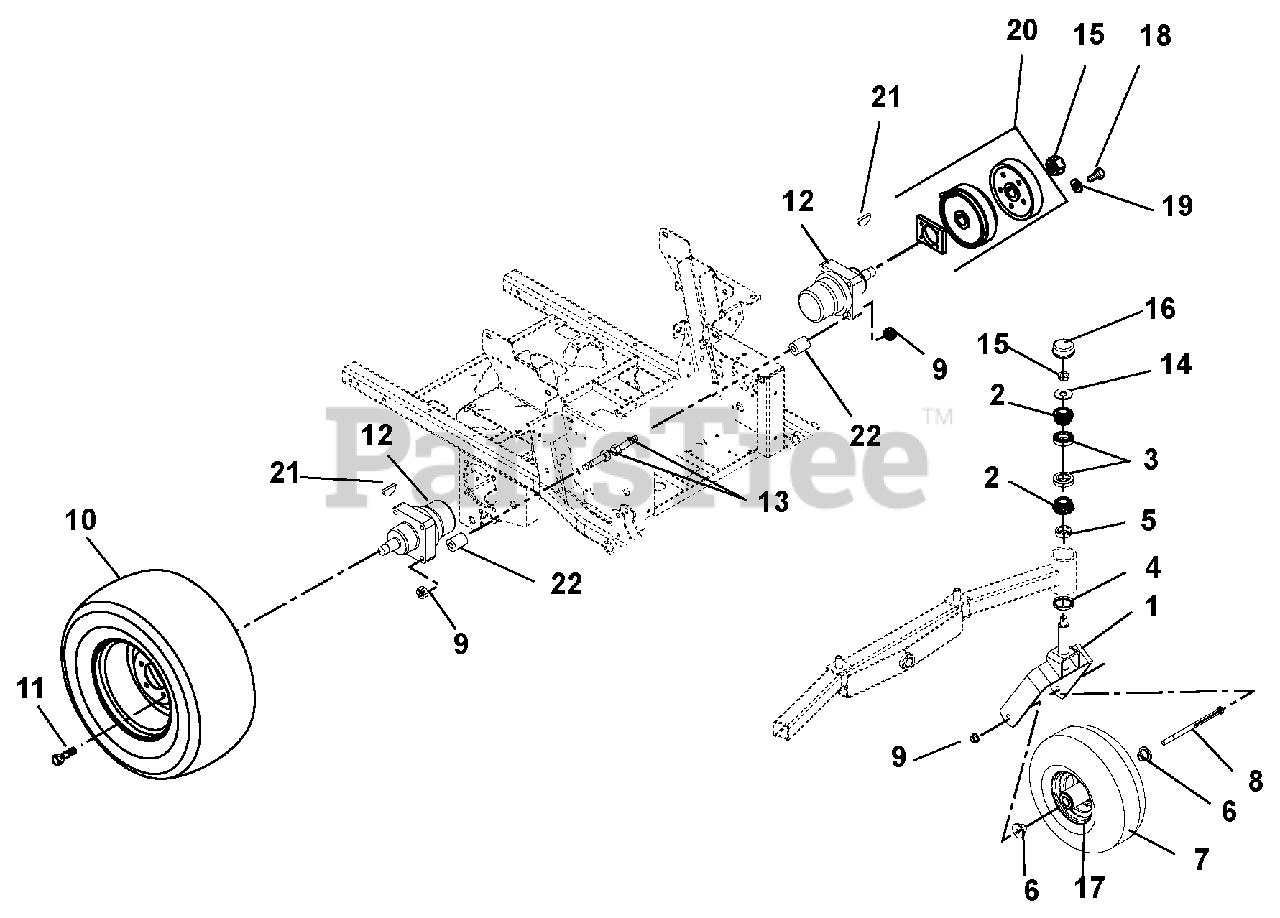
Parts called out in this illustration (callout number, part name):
1	Fork, Front
2	Bearing, Cone
3	Bearing, Cup 2.328 x .465
4	Bearing Seal 1.75 x 2.332 x .312
5	Spacer, 1.258ID x 1.750OD x .550
6	Spacer, Wheel
7	Wheel/Tire Assembly, 15 x 6-6, Smooth
8	Bolt, Hex .50-13 x 9.00 Grade 5
9	Nut, Locking Top Flange .50-13
10	Tire/Wheel Assembly, 24 x 11.50-12
11	Bolt, Lug .50-20 x 1.38
12	Wheel Motor, Parker
13	Bolt, Wheel Motor .50-13 x 5.00
14	Washer, Flat Steel .812 x 2.00 x .148
15	Nut, Locking Jam Patch 1.00-20
16	Cap, Dust
17	Bearing, 25mm ID x 52mm OD x 15mm
18	Bolt, Hex .31-18 x 1.50 Grade 8 EP30
19	Waher, Lock .31 x .078
20	Kit, Parking Brake Service
21	Key, Woodruff .31 x 1.00
22	Bushing, .513 x .748 x 2.129
